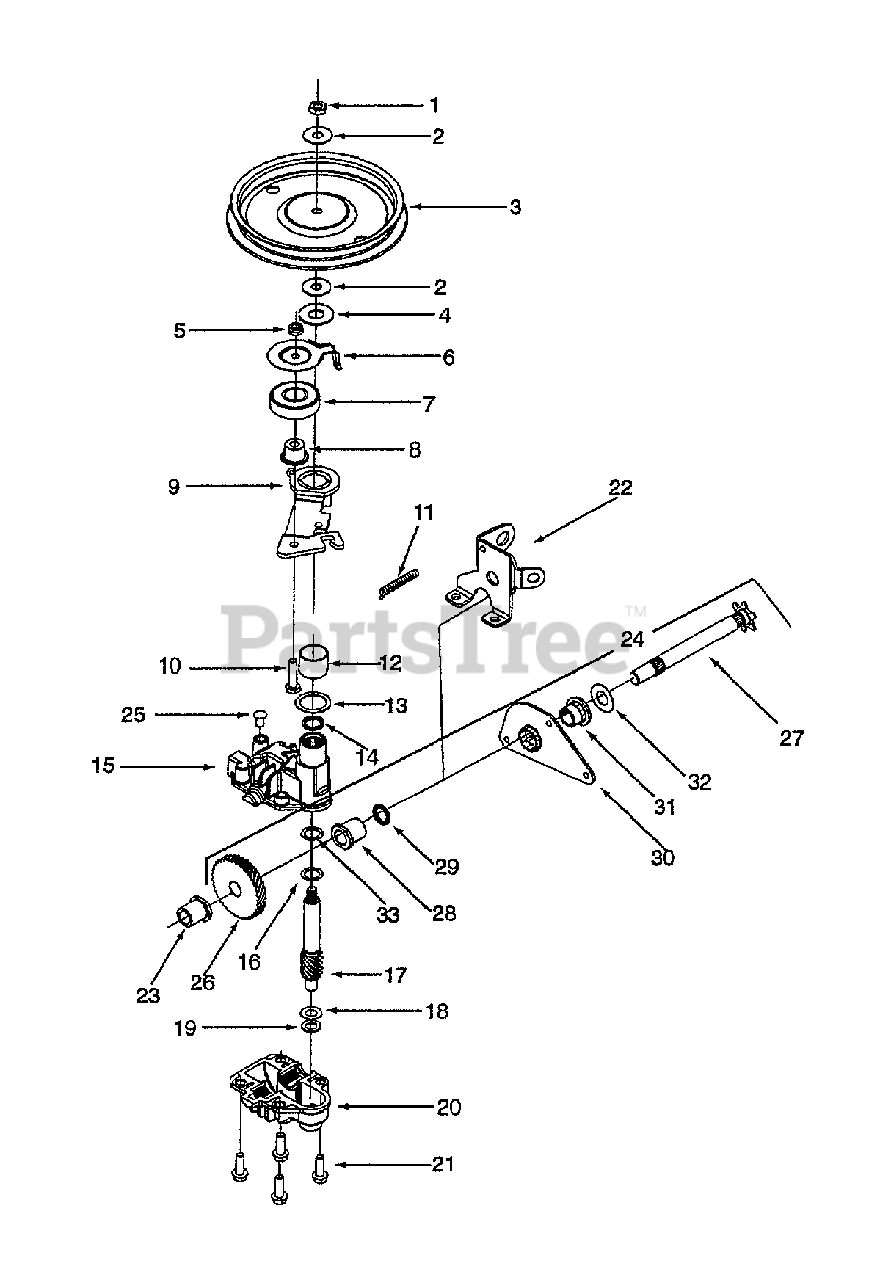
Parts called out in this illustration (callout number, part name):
1	Hx. Jam Nut 5/16-24
2	Bell Wash. .325 x .930 x .045
3	Pulley
4	Fl. Wash. .510 x 1.120 x .060
5	Hx. Jam Nut 1/4-28
6	Belt Keeper
7	Bearing
8	Flange Spacer
9	Idler Bracket Ass'y.
10	Hx. Cap Scr. 1/4-28 x 1.00 Gr. 5
11	Torsion Spring
12	Bearing Sleeve
13	Fl. Wash. .885 x 1.145 x.030
14	Oil Seal
15	Upper Housing Ass'y.
16	Fl. Wash. .504 x .700 x .030
17	Pinion Shaft 10 T
18	Thr. Wash. 3/8 x .70 x .030
19	Thr. Wash. .388 x .625 x .062
20	Lower Housing Ass'y.
21	Hx. Scr. 1/2-20 x .75
24	Shaft Ass'y.
26	Gear 34 T.
27	Output Shaft 6 T.
28	Flange Bearing
29	Oil Seal
30	Pivot Bracket
31	Flange Bearing
32	Wash. Fl. .508 I.D. x 1.00 O.D. x .020
33	Thrust Bearing
